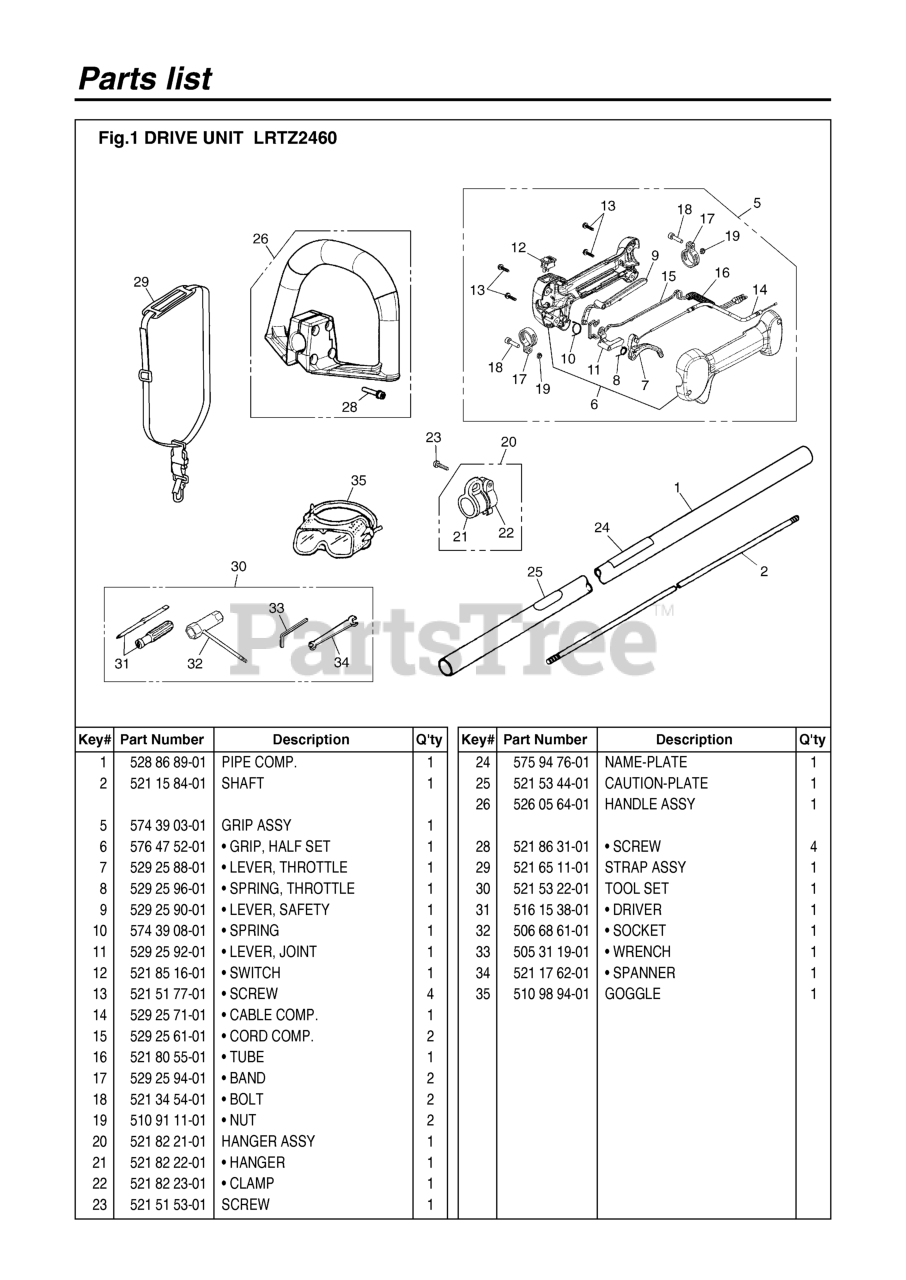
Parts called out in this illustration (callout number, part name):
1	PIPE COMP.
2	SHAFT (RPLS -122
5	GRIP ASSY
6	GRIP, HALF SET
7	LEVER, THROTTLE
8	SPRING, THROTTLE
9	LEVER FOR GRIP (
11	LEVER JOINT
15	CORD - C
18	BOLT (RPLS 28501
19	NUT
20	HANGER COMP.
21	HANGER
24	NAME PLATE
25	LABEL (CAUTION)
26	HANDLE ASSY. (RP
29	STRAP ASSY
30	TOOL-SET
31	SCREWDRIVER
34	SPANNER,8 x 10(R
35	GOGGLExxx (RPLS
